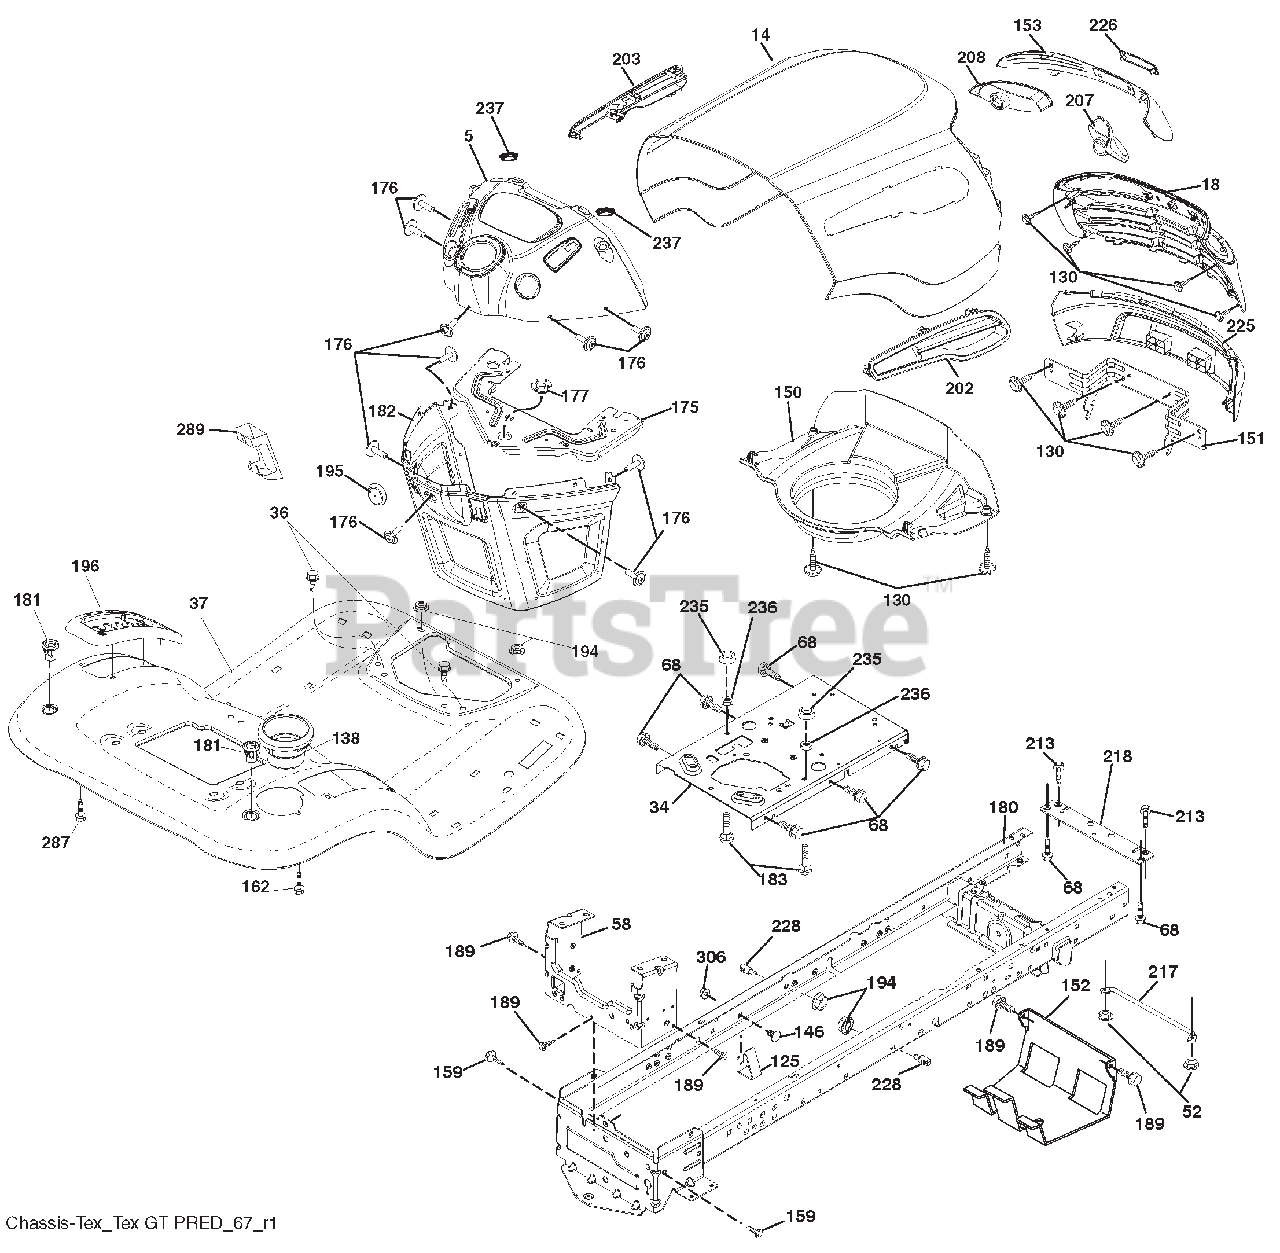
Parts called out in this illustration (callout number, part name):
5	DASH P/L TEX CABLE
18	GRILLE.ELITE.ARIENS.BLACK
34	PLATE.ENGINE.WELDED.CHASSIS
36	SCREW.5/16-18X3/4.SMGML.TAP/R
37	FENDER TLT W/CPH W/FW 422
52	Nut, Hex, Crownlock 5/16-18
58	DRAWBAR.UPPER.2PC.SML.FENDER
68	SCREW.THDROL.5/16-18 X 1/2TYTT
125	CLIP.FUEL.LINE
138	CUPHOLDER TL TEX 428
150	AIR DUCT
151	BRACKET.PIVOT
152	SHIELD.BROWNING.W/TEX
153	LENS.BAR
159	SCREW.HEXWSH THDR3/8-16X3/4.BL
162	SCREW.HEX.WSH.HI-LO.1/4X1/2UNC
175	CROSSMEMBER.LT
176	SCREW.#10-24X5/8.RND.QUDRX.GIM
177	BUSHING.STEERING.YT/GT
180	CHASS.WLDMT.TL.12GA/2PC.18/22"
181	BUSHING MNT FEND CRGO BLK TEX
182	DASH.LOWER.LT.CCS
183	BOLT.FIN.HEX.5/16-18 UNC X1-1/
189	SCREW.5/16-18X3/4.SMGML.TAP/BL
194	Nut, Lock Hex Flange 5/16-18 u
195	PLUG HOLE DASH TOWER
196	CONSLE.ASM.DECK.LFT.BL/RBT.TLT
202	VENT RH
203	VENT.SIDE.LH
207	BEZEL.RH
208	BEZEL.LH
213	Bolt, Hex Head 5/16-18 x 3/4
217	ROD.PIVOT.HOOD
218	X-PIECE.HOOD.STOP.NON/STEALTH
226	ARIENS.LOGO.PLATE
228	STUD.FASTNER.W/'D'ANTI-ROTATIO
235	SPACER.FENDER
236	NUT.CENTER LOCK.5/16-18 UNC
237	PLUG.MOUNT.CARGO
287	SCREW.HEX.WASHEAD.1/4-20 X 3/8
289	PLUG.CRUISE.CONTROL
306	Nut, Hex, Flangelock 3/8-16
